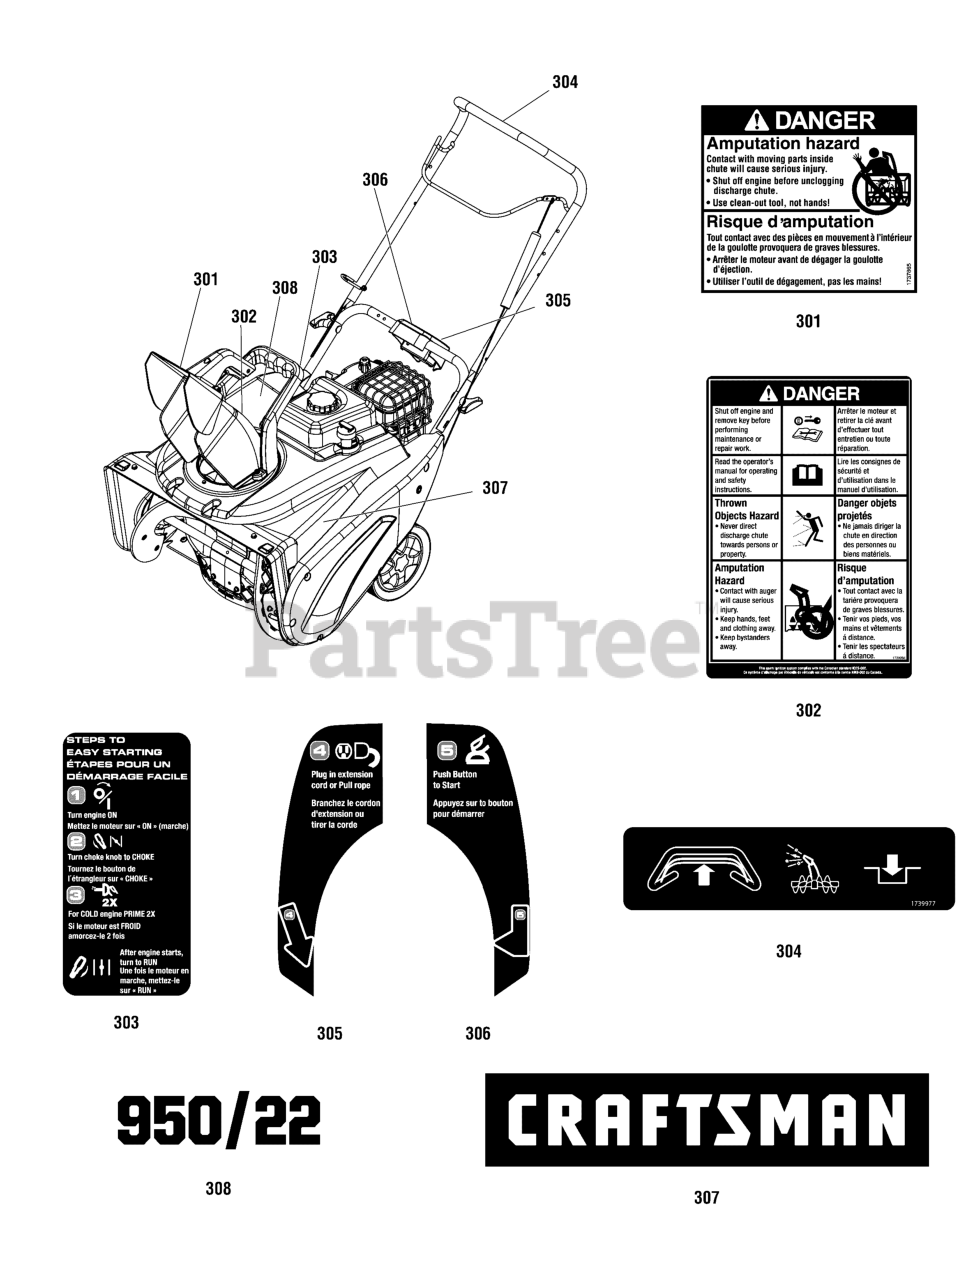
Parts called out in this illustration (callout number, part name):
301	DECAL, Danger Chute Warning, FR/ENG
302	DECAL, Chute, FR-EN
303	DECAL, 1-2-3 Start, FR-EN
304	DECAL, Bail Engagement
305	DECAL, 4, START, FR-EN
306	DECAL, 5, START, FR-EN
307	DECAL, Craftsman Logo
0340	KIT-DECAL SHEET
